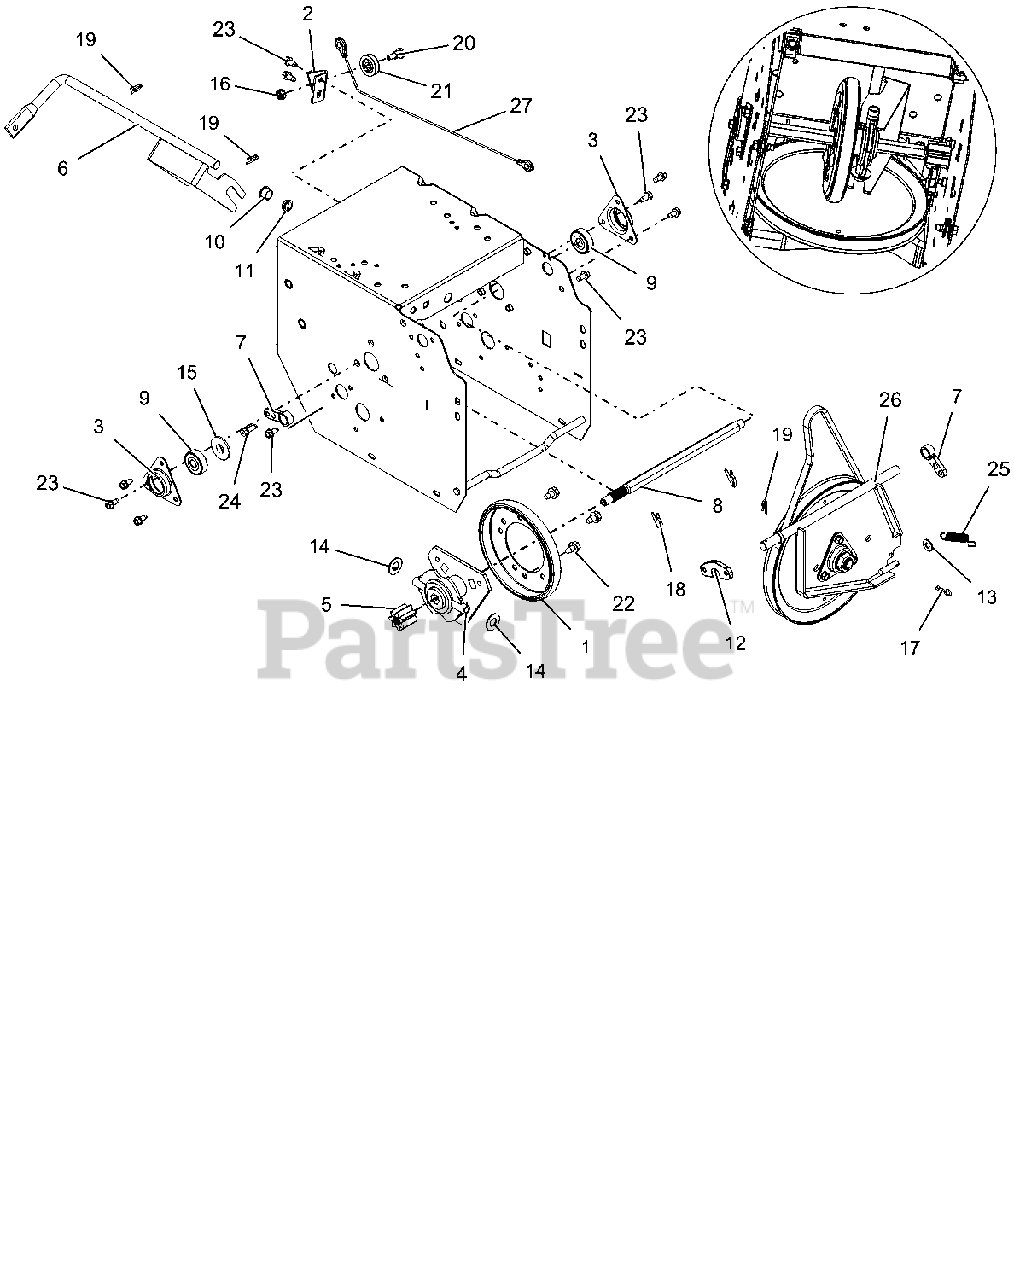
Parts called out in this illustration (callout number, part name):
1	FRICTION, DISC
2	BRACKET, CABLE PULLEY
3	FLANGE, BEARING
4	CARRIER, DRIVE DISK
5	GEAR, PINION, 7 TOOTH W/SPLINE
6	WELDMENT, SHIFT FORK
7	SUPPORT BUSHING, SWING GATE
8	SHAFT, HEX W/SPLINE
9	BRG-BALL .437X1.375X.437
10	BUSHING, POLYLINER-.50 SPLIT
11	BUSHING, POLYLINER-.50 SNAPIN
12	SPACER, SWING GATE
13	@WSHR-FL-STL.344X.688X.065YWZC
14	WSHR-FL-STL .505X1.00X.062YWZC
15	@WSHR-FL-STL.563X1.38X.109YWZC
16	@NUT-LK-CTR-FLG .25-20 YWZC
17	PIN-HAIR INT .08X.18X1.18 YWZC
18	PIN, SPRING CLIP
19	CLIP, SPRING
20	BOLT, SHLDR-.375X.375X.25-20
21	PULLEY, CABLE
22	@SCR-TAP .31-18X.50 HWH TR YWZ
23	SCR-TAP .25-20X.50 HWH TR YWZ
24	SCR-TAP-PM .25-20X.75 TR YWZ
25	SPRING, EXT. .043X.438X1.64
26	PLATE, SWING - ASSEMBLY
27	CABLE, LOWER TRACTION (CMPCT)
